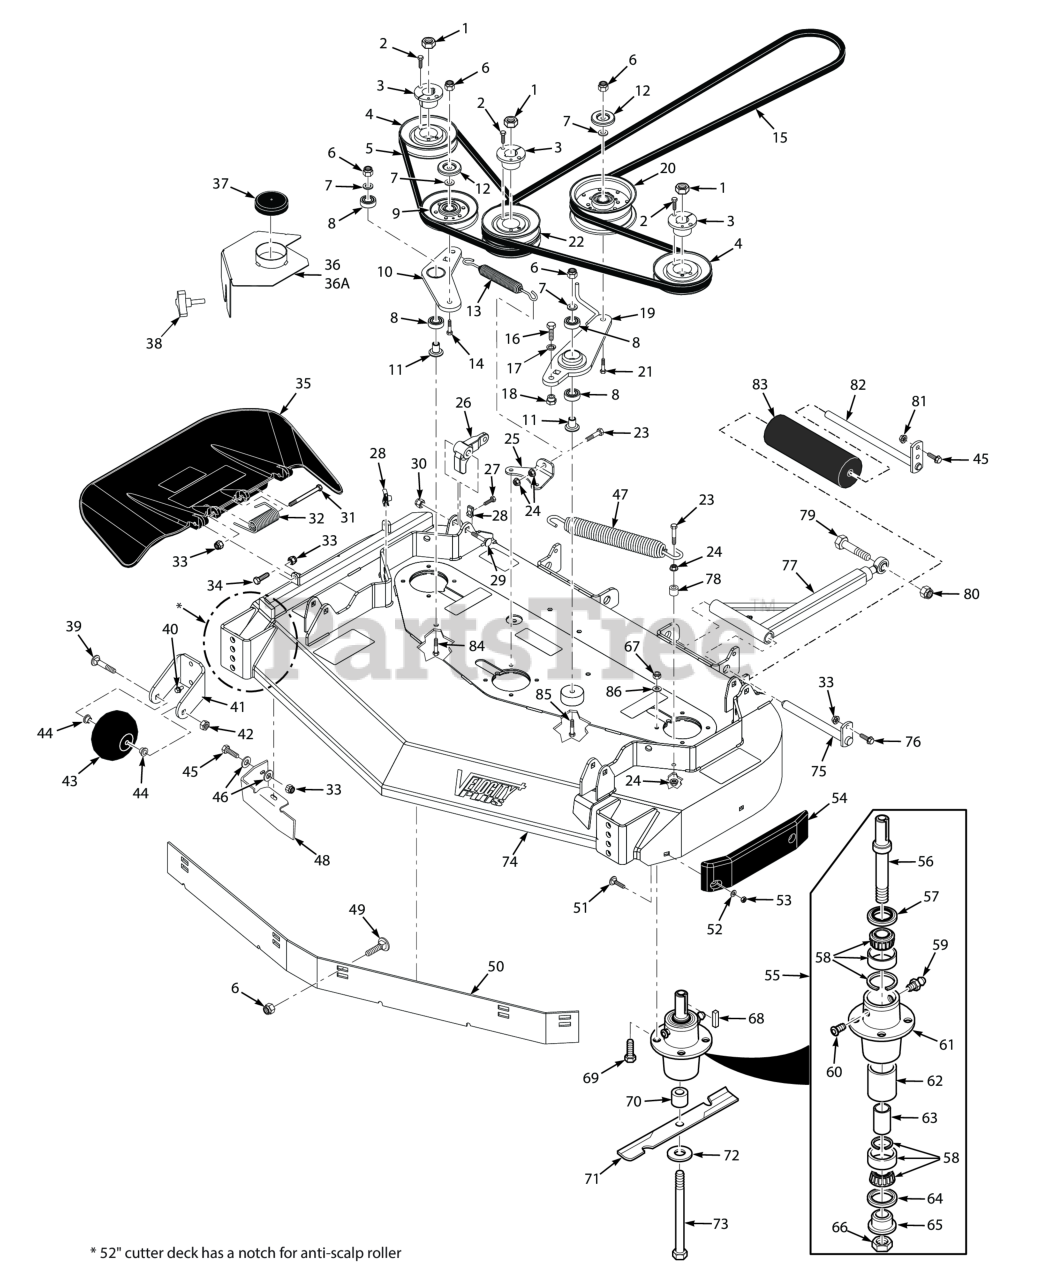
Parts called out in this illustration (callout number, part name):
1	Hex Locknut, Elastic Stop, 3/8-16
2	Bolt, Hex Head 1/4-20 x 1" Grade 8 Black
3	Hub, Tapered 1-1/8" Bore
4	Pulley, 5.73 OD Tapered Bore
5	Belt, R.H. Cutter Deck
6	HEX NUT, ELASTIC STOP LOCK, 3/8-16
7	Flatwasher, 3/8 (.391 x .938 x .105 HD) Grade 8
8	BEARINGS, BALL, NEUTRAL RETURN
9	IDLER PULLEY, "V" GROOVE
10	ldler Arm Assembly, R.H. Drive
11	Pivot, Idler Short
12	Quick Pin, 5/16" Dia.
13	Spring, Idler R.H.
14	Capscrew, Hex Head 3/8-16 x 2.0"
15	Belt, Cutter Deck Drive (52V)
16	Bolt, Hex Head 7/16-14 x 1"
17	Lockwasher, 7/16� Spring
18	Boss, Spring Anchor - LH
19	Idler Arm Assy.
20	Pulley, Idler 5" Dia.
21	Bolt, Hex Head 3/8-16 x 3" - 52"
22	Pulley, Double Groove
23	Bolt, Hex Head 3/8-16 x 1-1/2" Grade 8 Black
24	NUT, 3/8-16 SERRATED FLANGE HEX HEAD
25	Bracket, Spring Anchor RH (52V)
26	Lever, Deck Level
27	Bolt, Hex Head 3/8-16 x 2" Special Lock
28	U-Nut, 3/8-16 (short)
29	Bolt, Carriage 7/16-14 x 2-1/4"
30	HEX LOCKNUT, ELASTIC STOP, 7/16-14
31	Bolt, 5/16-18 x 4-3/4" Hex Head
32	Spring, Discharge Chute
33	HEX NUT, ELASTIC STOP LOCK, 5/16-18
34	Bolt, Hex Head 5/16-18 x 1-1/2" - Front
35	Discharge Chute Assembly - 52V
35	Discharge Chute Assy. (CA)
36A	Belt Cover Weldment RH
36A	Belt Cover Weldment LH
38	Knob, w/stud 3/8-16 x 1-1/4"
39	Bolt, Hex Head 3/8-16 x 3-1/2"
40	Capscrew, 3/8-16 x 1.0" Serrated Flange Hex Hd
41	Bracket, Anti-Scalp Wheel
42	Bolt, Hex Head 3/8-16 x 1" Ser. Flg.
43	Bolt, Carriage 3/8-16 x 4"
44	Bushing, .376" I.D. Oilite
45	Bolt, Heax Head 5/16-18 x 1" (48V / 52V)
46	Flatwasher, 5/16-.375 x .875 x .083 (35BV & 37BV-EFI)
47	Spring, L.H. Deck Drive
48	Turbo Baffle - 48V / 52V
49	Carriage Bolt, 3/8-16 x 1.0"
50	Baffle Custom-Cut, 52V (7-Position)
51	Bolt, 5/16-18 x .75 RHSN Carriage
52	Flatwasher, 5/16-.344 x .688 x .065 (48V / 52V)
53	Nut, Center Lock, 5/16-18(32)
54	Pad, Deck Wear
55	Cutter Spindle Assembly
56	Spindle Shaft, Tapered Brng
57	SEAL, 2.00 O.D. X 1.50 BORE
58	Tapered Bearing Set (Two Bearings W/Race)
59	GREASE FITTING, STR. 1/4-28 SELF TAP.
60	RELIEF FITTING, TAPERED BEARING SPINDLE
61	Housing, Spindle
62	Spacer, Outside, Cutter Spindle
63	SLEEVE, CUTTER SPINDLE
64	Seal, 2.00" O.D. x 1.625" Bore
65	SPINDLE BUSHING, BOTTOM
66	Nut , Spec ial 1 -1/ 1 6 - 1 8
67	Lock Nut, 5/16-18 Elastic Stop Grade 8
68	Key, 1/4 x 1/4 x 2.0"
69	Bolt, Hex Head 5/16-18 x 1-3/4" Grade 8
70	Spacer, Spindle Bottom
71	Cutter Blade, 18" (52V)
72	Flatwasher, 5/8-.688 x 1-3/4 x .134 HD
73	BOLT, HEX HEAD, 5/8-11 X 9-1/2 GR.5
74	Cutter Deck Velocity Plus
75	Shaft Weldment, Pusharm
76	Bolt, Heax Head 5/16-18 x 1" (48V / 52V)
77	Push Arm (Includes 64,60,62)
78	SPACER, IDLER
79	BOLT, HEX HEAD 5/8-11 X 4-1/2"
80	HEX LOCKNUT, ELASTIC STOP, 5/8-11
81	Nut, Flange Head Elastic Stop 5/16-18
82	Shaft Weldment, Guide Roller
83	Wheel, Anti-ScalpRelief Fitting, Tapered Spindle
84	Bolt, Hex Head 3/8-16 x 2-1/4" - 61"
85	Capscrew, Hex Head 3/8-16 x 3.25"
86	Lockwasher, 5/16 (.317 x .586 x .078) Helical Spring
